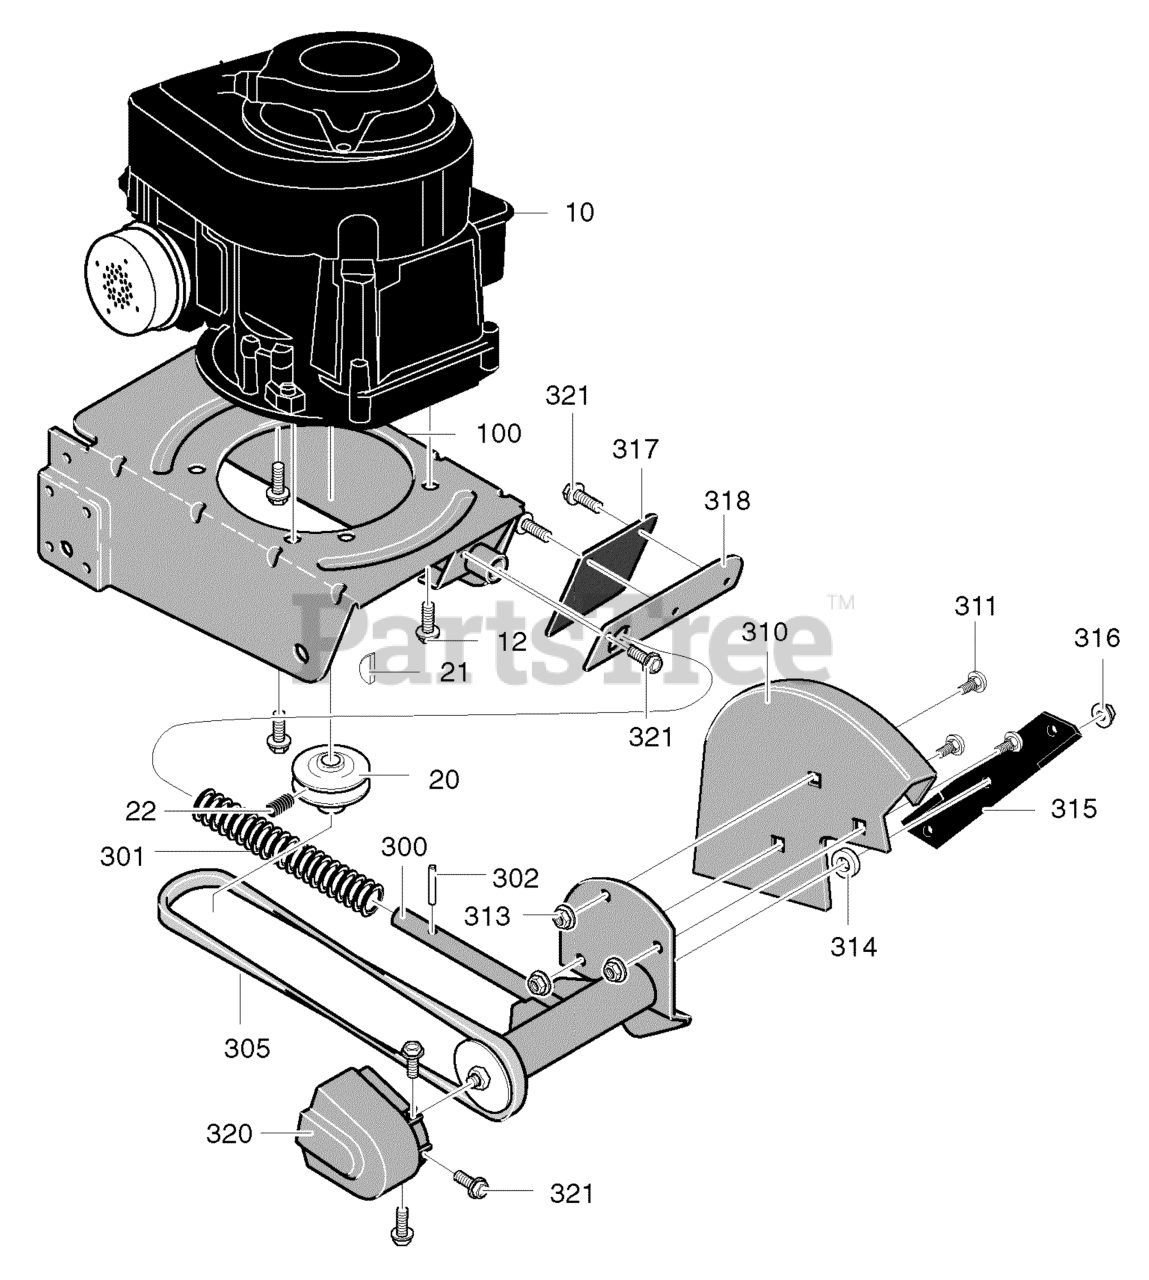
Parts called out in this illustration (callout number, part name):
12	Screw
20	Pulley, V3L
21	Key, Hi Pro #505
22	Screw, Set
100	Frame, Edger
300	Quill Assembly
301	Spring
302	Spring Pin
305	Belt, V4L
310	Blade Guard
311	Bolt, Carriage
313	NUT, 5/16-18
314	Flat washer
315	Blade, Edger
316	NUT, 1/2-20
317	Deflector, Rubber
318	Plate, Rubber Flap
320	Belt Guard
321	Screw, 10-16x.50
